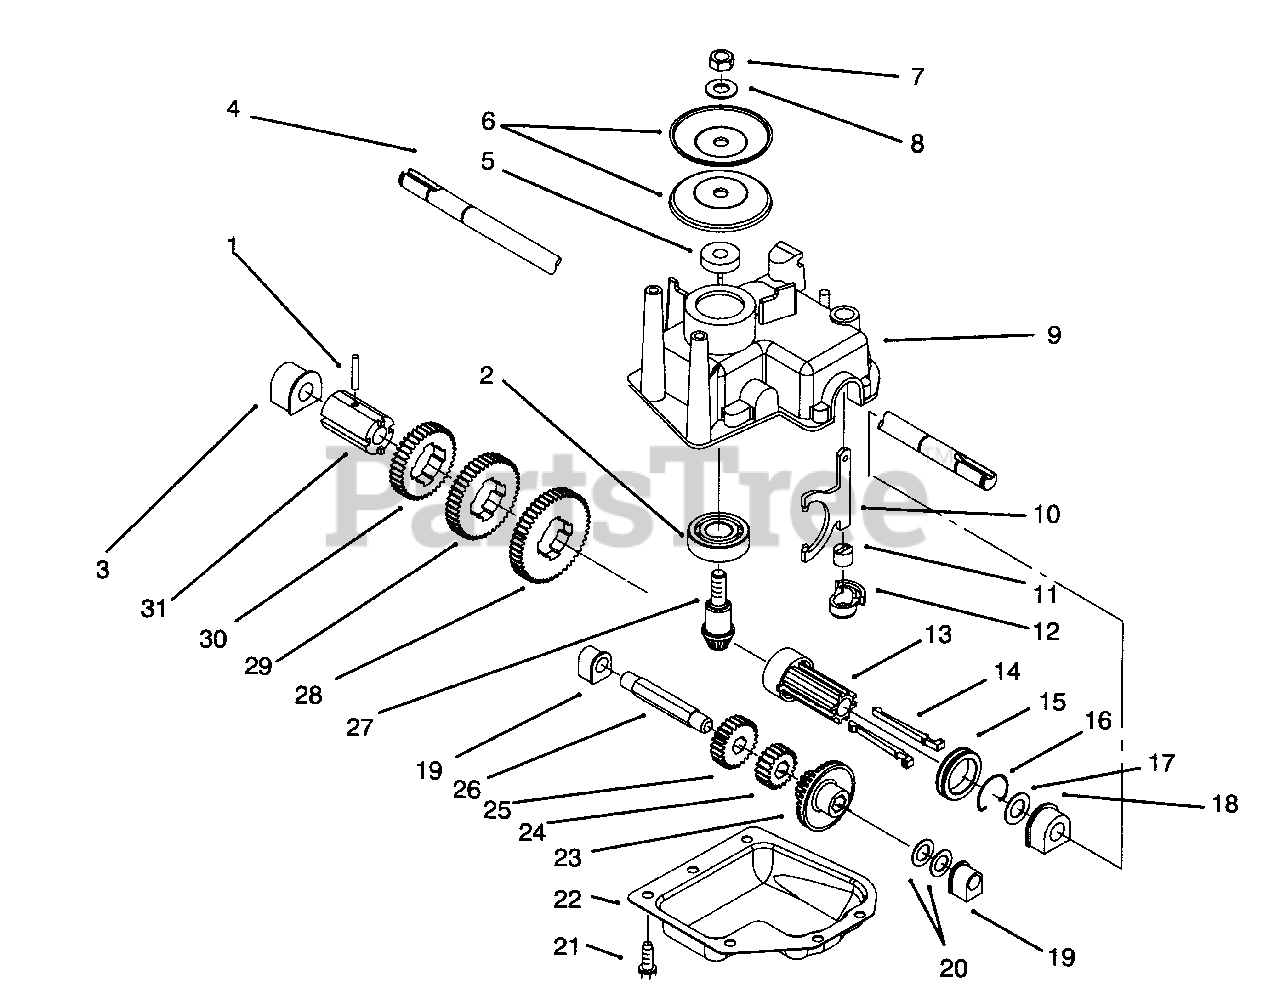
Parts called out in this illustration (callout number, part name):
1	Pin-Groove
2	Bearing-Ball
3	Bushing-Output
4	Shaft-Output
6	Pulley-Half
9	Gearcase-Upper
10	Yoke-Shift
11	Bushing-Yoke
12	Retainer-Shift Fork
13	Sleeve-Shift Key
14	Key-Shift
15	Collar-Shift
16	Clip-Spring
18	Bushing-Output
19	Bushing-Inter. Shaft
20	Washer-Thrust
22	Gear Case Cover
23	Pinion-15 Tooth
24	Pinion-20 Tooth
25	Pinion-25 Tooth
26	Shaft-Intermediate
27	Pinion-Bevel
28	Gear-49 Tooth
29	Gear-44 Tooth
30	Gear-39 Tooth
31	Sleeve-Gear
